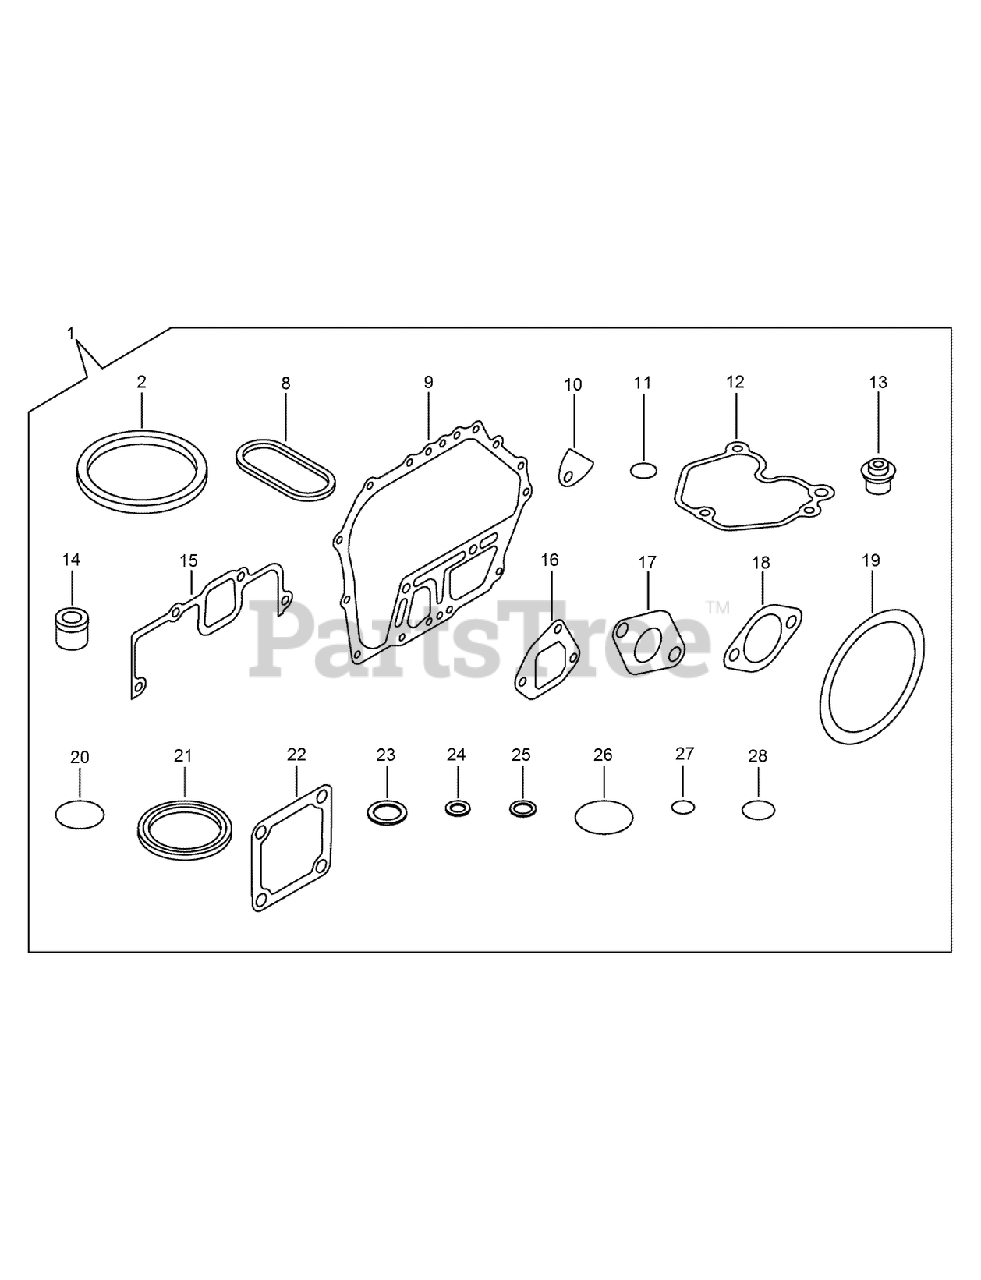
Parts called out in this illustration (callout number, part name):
1	GASKET SET
2	GASKET-HEAD, CYLINDER
8	O RING-TAPPET
9	GASKET-CASE, CRANK
10	GASKET-COVER
11	O-RING
12	GASKET-COVER
13	SEAL-STEM, VALVE
14	GASKET-NOZZLE
15	GASKET-CLEANER, AIR
16	GASKET-CLEANER, AIR
17	GASKET-MUFFLER
18	GASKET-MUFFLER
19	GASKET
20	O-RING
21	GASKET
22	GASKET
23	WASHER-SEAL
24	GASKET
25	GASKET
26	O-RING
27	O-RING
28	O-RING
